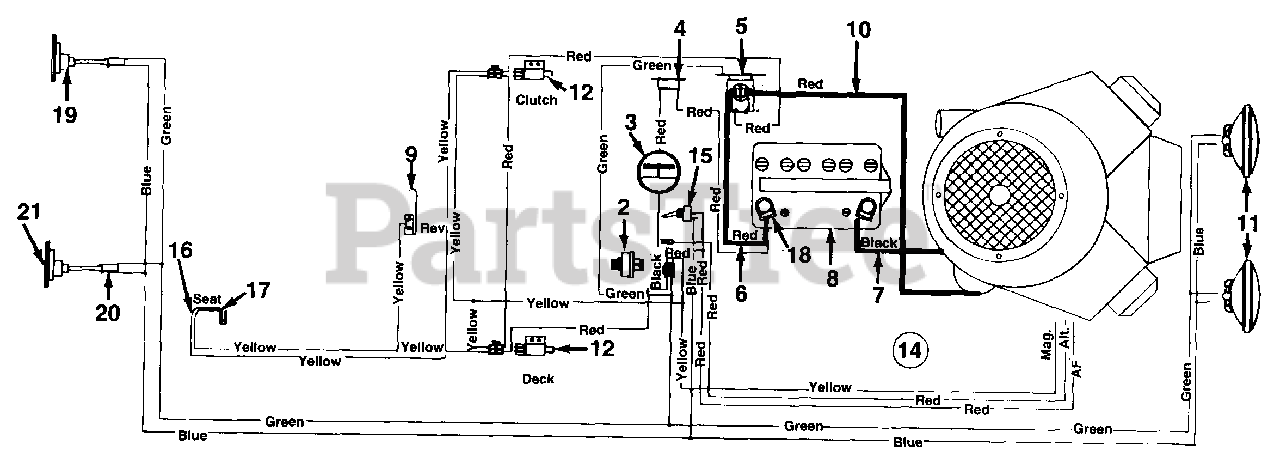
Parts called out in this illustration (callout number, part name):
2	Ignition Switch
3	Ammeter
4	Circuit Breaker 20 Amp
5	Solenoid
6	Electric Wire
7	Electric Wire
8	Battery
9	Spring Switch (Reverse Safety)
10	Electric Wire
11	Headlights
12	Safety Switch (PTO & Clutch)
14	Wire Harness
15	Light Switch
16	Safety Switch (Seat)
17	Safety Switch (Seat)
18	Battery Boot
19	Tail light
20	Tail light Harness
21	Tail light Bulb
